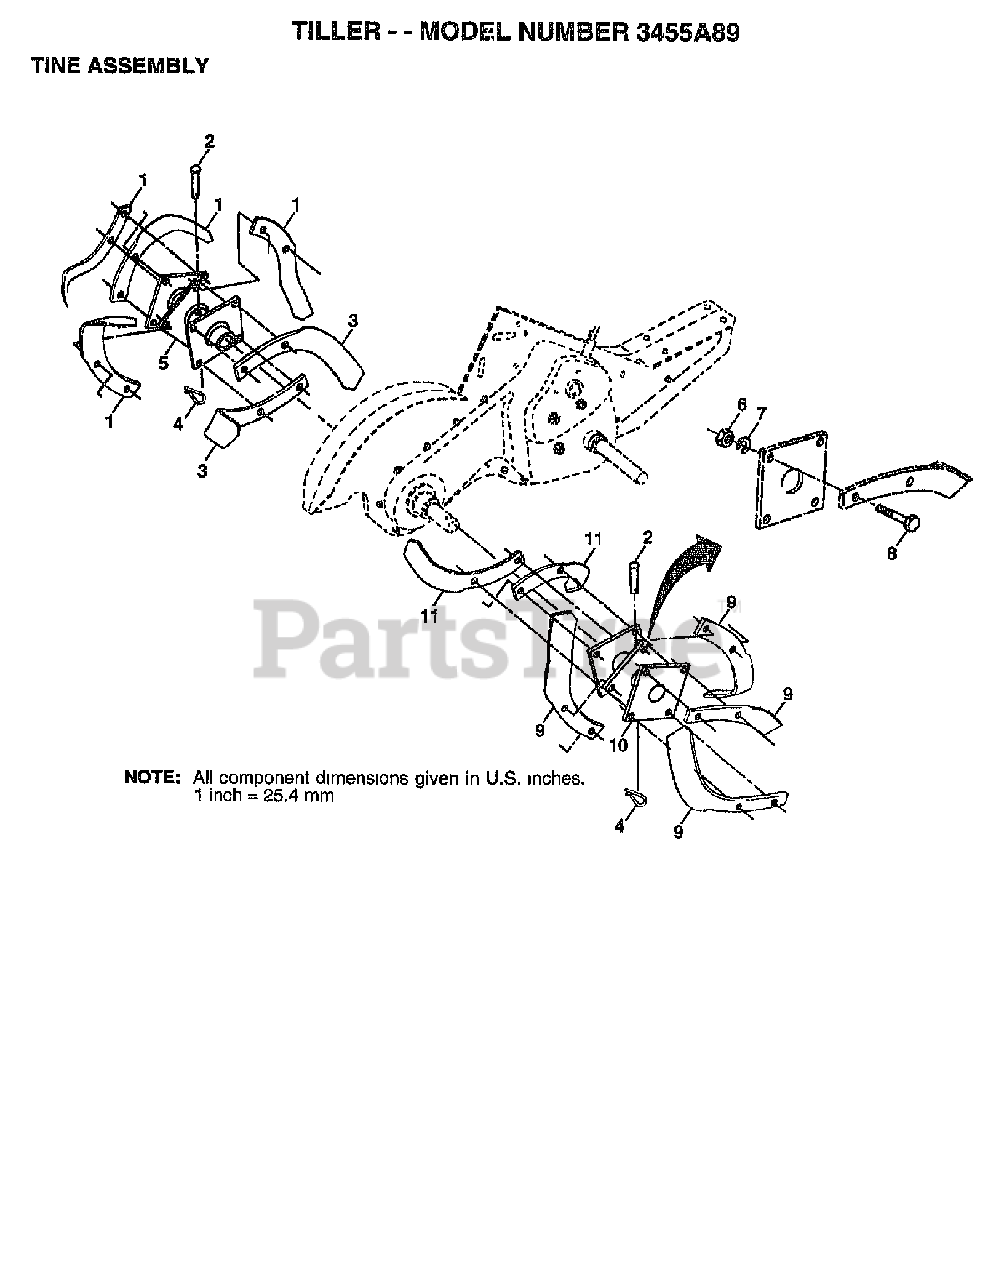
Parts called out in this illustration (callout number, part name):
2	CLEVIS PIN
3	TINE.LH.12"
4	SPRING RETAINER
5	HUB.&.PLATE.ASM.LH
6	NUT
7	WASHER, LOCK 3/8
8	BOLT.HEX.001X20.37-24X1.ZINC
10	HUB & PLATE ASM RH
11	TINE.RH.12"(72R)
